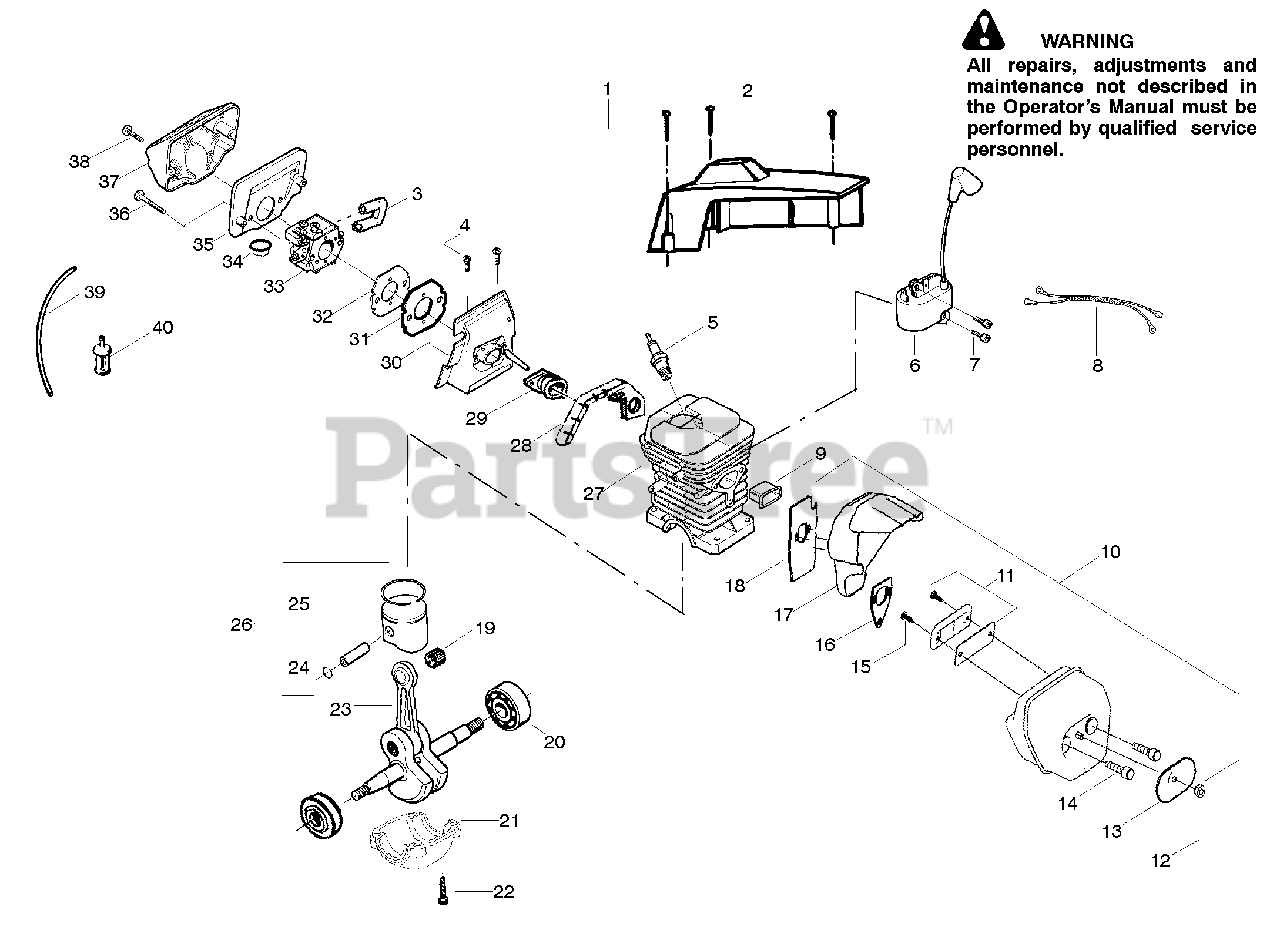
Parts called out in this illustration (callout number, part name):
2	Kit-Cylinder Shield
3	Grommet -Carb.
5	Spark Plug (RCJ-7Y)
6	Module-Ignition
8	Assy-Switch Wire
9	Insulator-Heat
10	Kit-Muffler
11	Kit-Spark Arrestor
12	Nut-Brass
15	Screw-Spark Screen
16	Gasket-Muffler
17	Assy-Muffler Backplate
18	Backplate - Alum.
19	Bearing-Piston Pin
20	Assy-Bearing & Seal
21	Cap-Crankcase
23	Assy-C’shaft & Rod
24	Retainer-Piston Pin
26	Kit-Piston
27	Assy-Cyl/Crankcase
28	Seal-Super Clean
30	Adapter-Carb.
31	Intake Plate-Carb
33	Kit-Carburetor (WT-657)
35	Filter-Air (Bottom)
37	Filter-Air (Top)
39	Kit-Fuel Line (Small)
40	Assy-Fuel Pick-up
